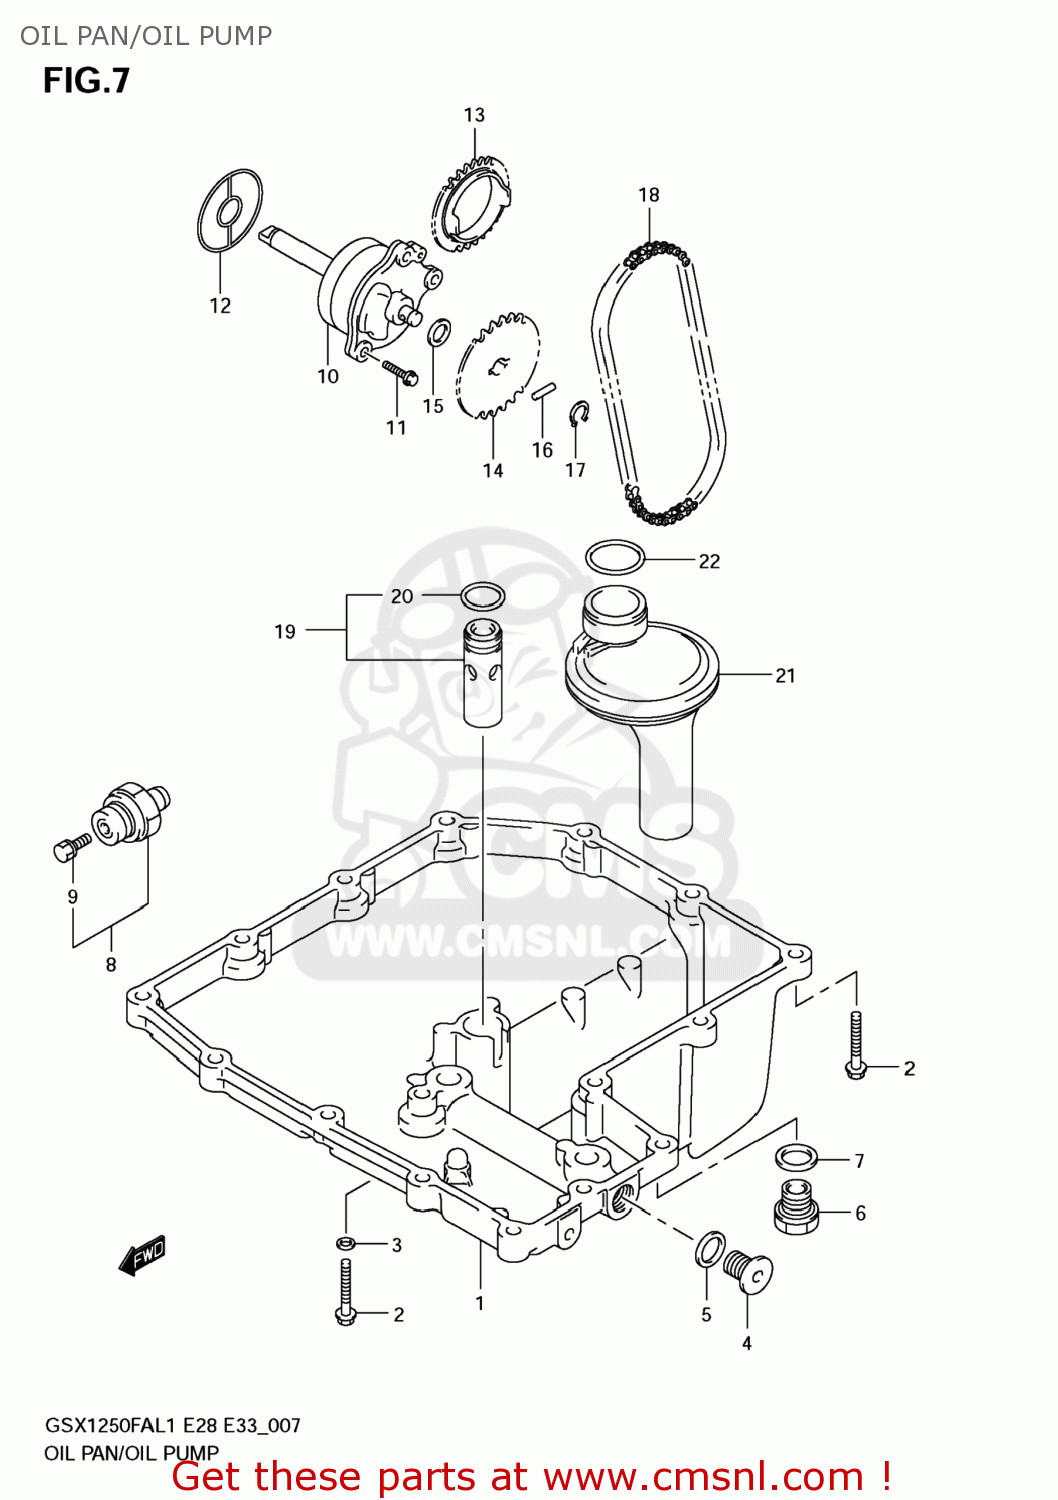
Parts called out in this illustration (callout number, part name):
1	PAN,OIL
2	BOLT
3	GASKET(5.8X13X1.2) (NAS)
4	PLUG(L:12)
5	GASKET(12.1X16.2X3.7) (NAS)
6	PLUG(14X20)
7	GASKET(13.8X18.8X4.8) (NAS)
8	SWITCH ASSY,OIL PRESSURE
9	BOLT,OIL PRESSURE SWITCH
10	PUMP ASSY,ENGINE OIL
11	BOLT
12	O RING,OIL PUMP
13	SPROCKET,OIL PUMP DRIVE
14	SPROCKET,OIL PUMP DRIVEN
15	SHIM(10X18X0.5)
16	PIN(4X15.8)
17	CIRCLIP
18	CHAIN,OIL PUMP DRIVE
19	VALVE ASSY,OIL RELIEF(7K)
20	O RING(D:1.9,ID:13)
21	STRAINER ASSY,ENGINE OIL
22	O RING(D:2.4,ID:24.7)
